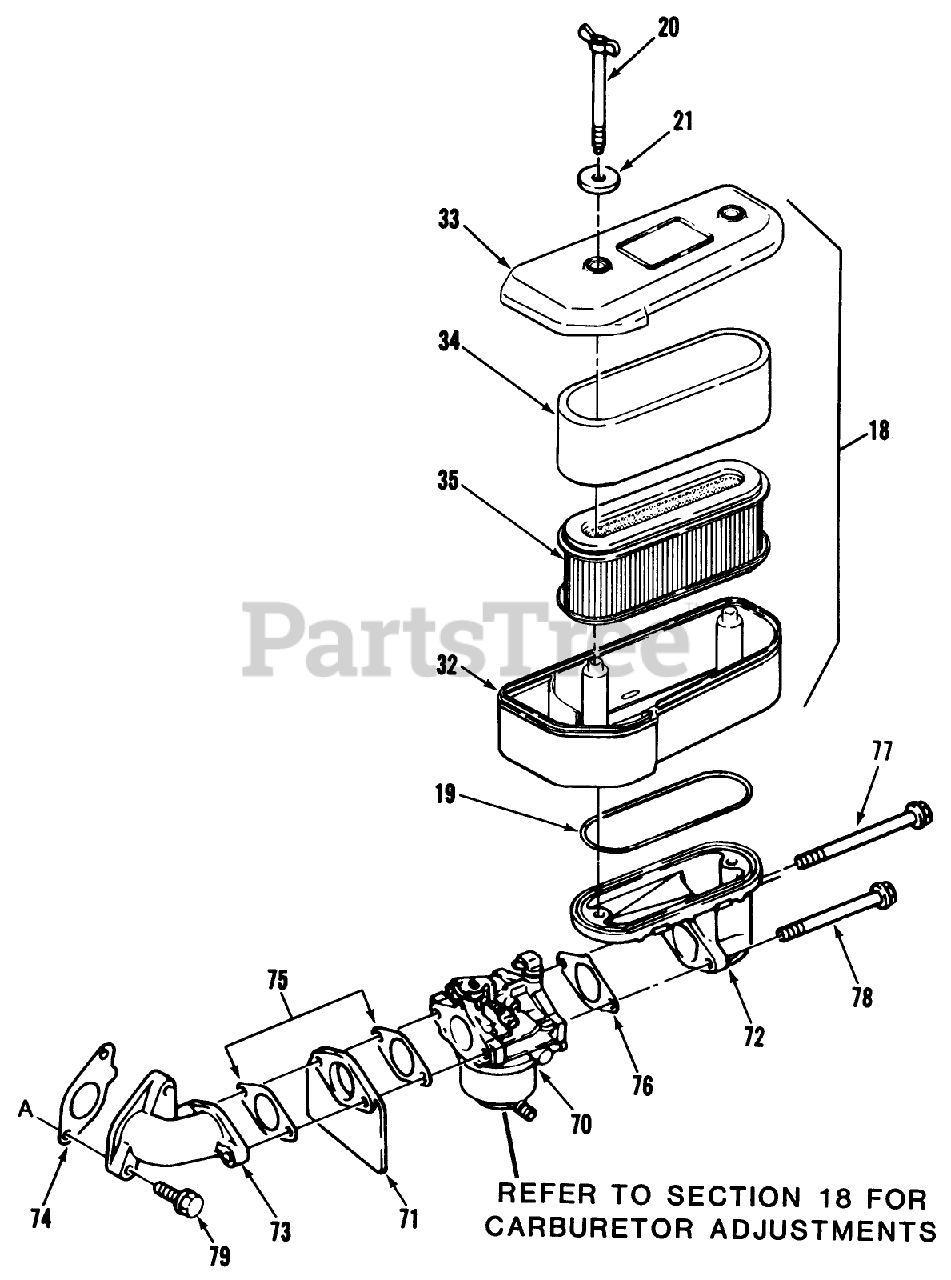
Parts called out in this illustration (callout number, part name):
18	Air Filter Assy (includes items 32, 33, 34 35)
32	CASE-Air Filter
33	CAP-Air Filter
34	Element
35	Element
70	Carburetor Assy-see section 9-6 for parts breakdown
71	Insulator
72	Pipe-Intake
73	Pipe-Intake
79	Bolt-Flanged (8X25)
